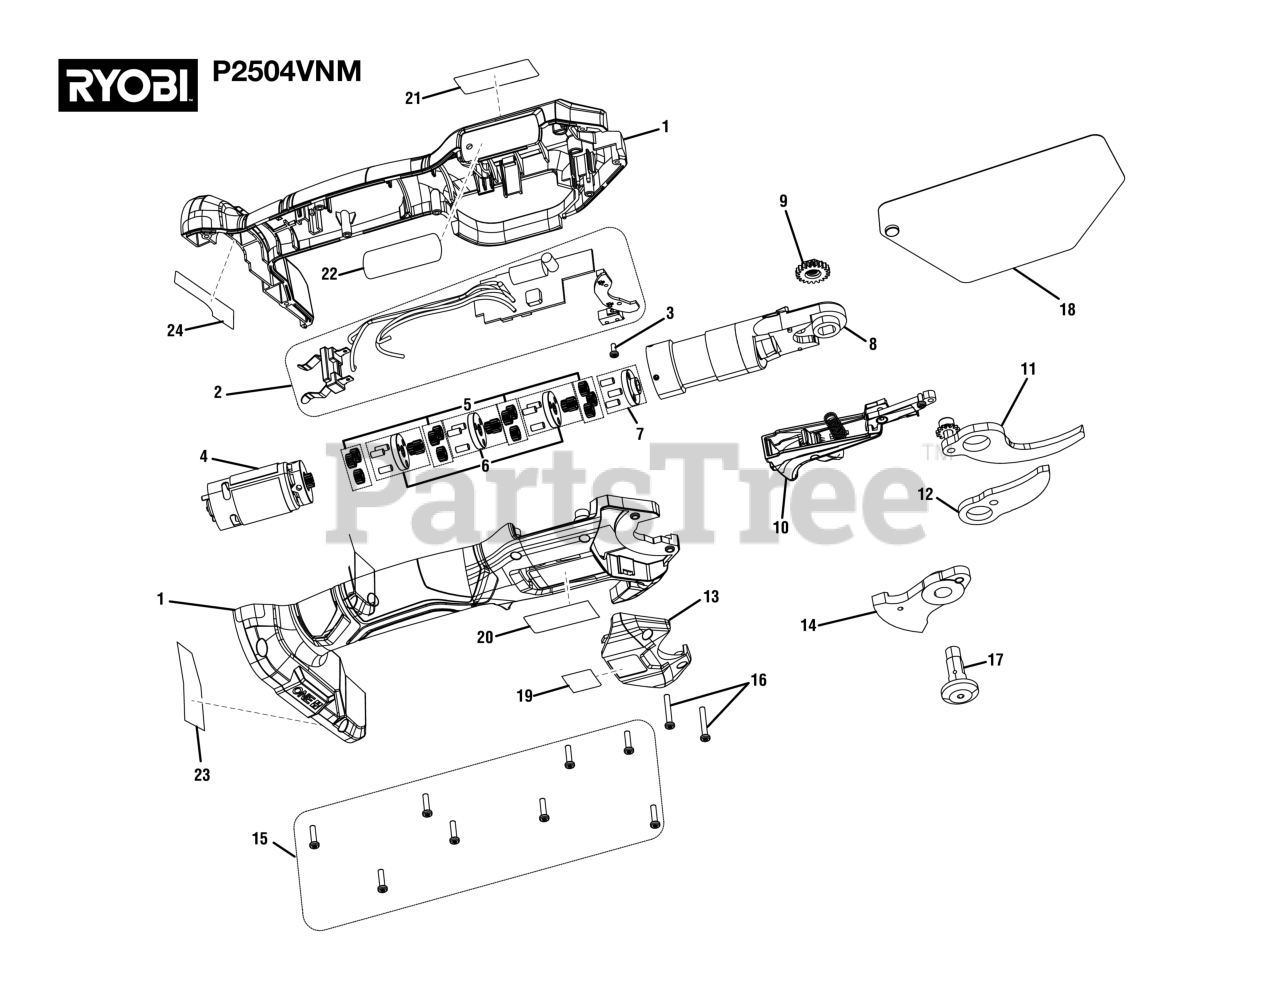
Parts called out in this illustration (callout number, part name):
1	Housing Assembly (Inc. Key Nos. 20-23)
2	Circuit Board Assembly
3	Screw (M2.5 x 8 mm)
4	Motor Assembly
5	Planet Gear
6	Planet Frame Assembly
7	Output Planet Frame Assembly
8	Gear Box Assembly
9	Screw with Gear
10	Trigger Assembly
11	Bottom Blade Assembly
12	Cutting Blade
13	Blade Cover (Inc. Key No. 19)
14	Bear Gear Assembly
15	Screw (M3 x 12 mm)
16	Screw (M3 x 20 mm)
17	Pivot Bolt Assembly
18	Blade Sleeve
19	Pinch Point Icon Label
20	Icon Label
21	Logo Label
22	Warning Label
23	Data Label
